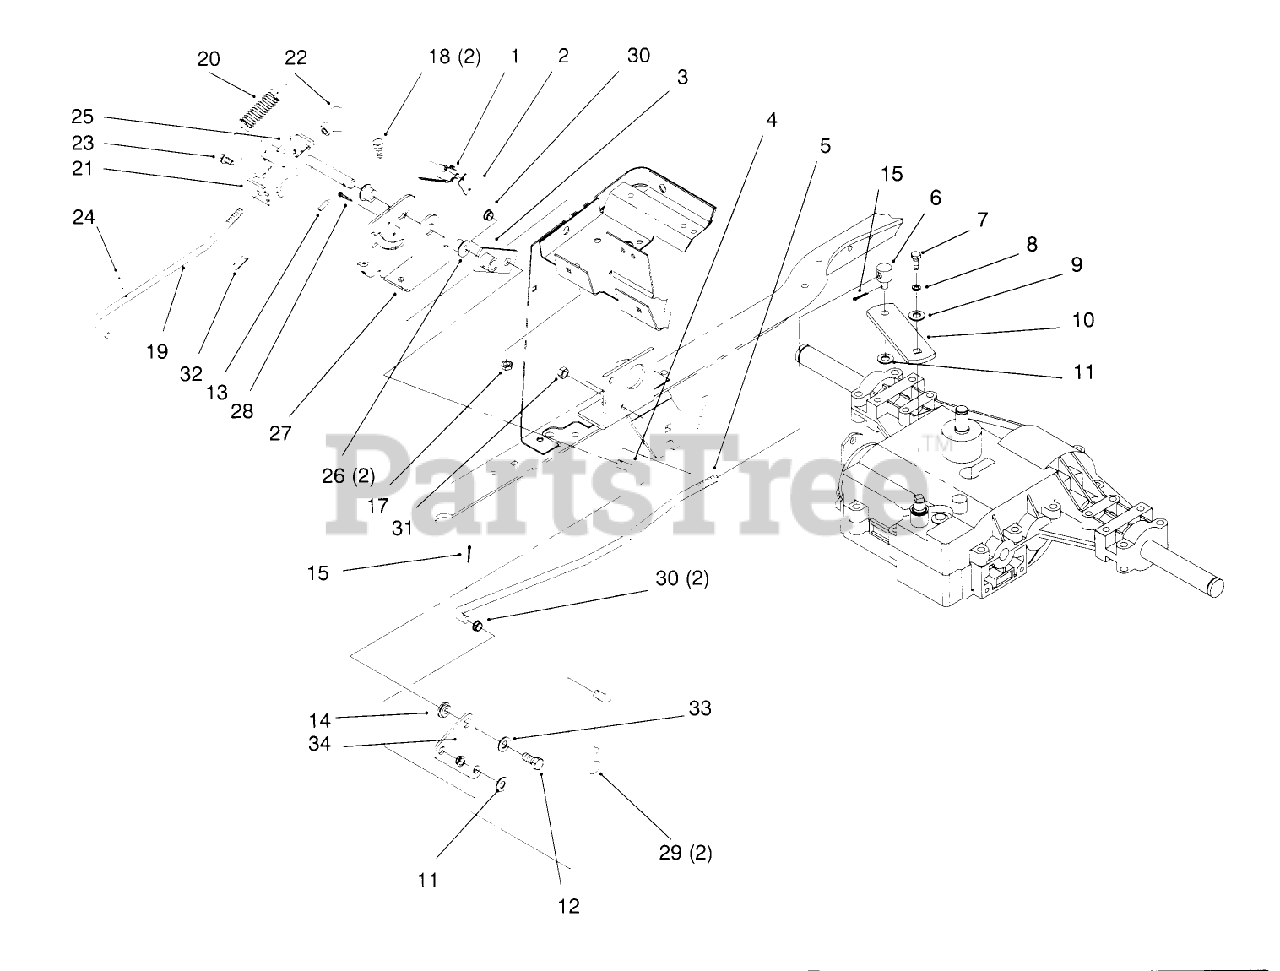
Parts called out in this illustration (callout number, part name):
1	SWITCH - CLUTCH
2	NUT-SPEED
4	ROD - LINKAGE
5	ROD - TRANSAXLE SHIFT
7	SCREW-HH
8	WASHER-LOCK
9	SPACER
10	BRK-TRASXL SHI
11	WASHER-FLAT
12	SCREW-HH
13	PIN-ROLL, SLOTTED
14	BUSHING
15	PIN-COTTER
17	NUT-LOCK, NI
18	SCREW-HH
19	ROD - SHIFT
20	SPRING-COMPRESSION
21	BRACKET - SHAFT
23	SCREW-HWH
25	PIVOT ARM WA PLATED
26	BUSHING
27	BRKT-PIVOT MTG
31	NUT-LOCK, NI
32	DECAL - REVERSE GEAR
32	DECAL - REVERSE SHIFT
33	WASHER-FLAT
34	BRACKET - PIVOT
